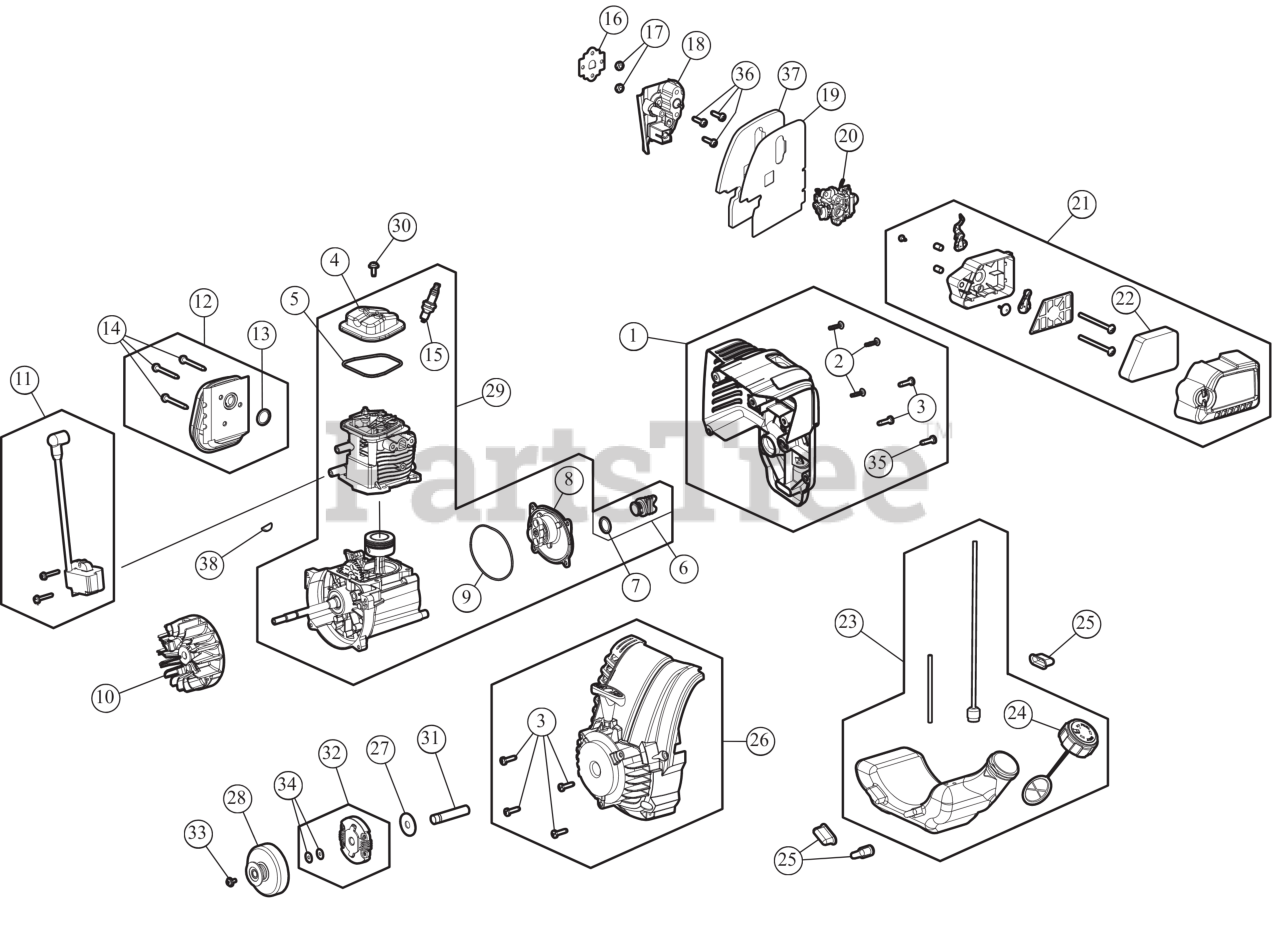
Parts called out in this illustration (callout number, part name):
1	REAR ENGINE CVR
2	SCREW 8-16 x 3/4
3	SCREW M5-0.8 x 19
4	ROCKER COVER
6	OIL PLUG
7	RING, OIL PLUG (AC
8	CRANKCASE COVER
9	O-RING CRNKCSE CVR
10	FLYWHEEL ASSEMBLY AC3.1
11	MODULE ASSEMBLY
12	MUFFLER ASSEMBLY
13	GASKET/MUFFLER
14	SCREW M5 x 44MM
15	SPARK PLUG 4 CYCL
16	GASKET/INSULATOR
18	CARB INSULATOR
20	CARBURETOR
21	AIR CLEANER COVER
22	AIR FILTER
23	FUEL TANK ASSEMBLY
24	FUEL CAP ASSEMBLY 43MM-6 W/O HOLE
25	FUEL TANK PADS
26	STARTER HOUSING
27	WASH, CLUTCH O.D. 1.155 +/- .0
28	CLUTCH DRUM/PULLEY
29	SHORT BLOCK
30	SCR, VALVE COVER
31	SPACER :2.165"
32	CLUTCH WITH SPACER
33	SCREW 8-32X.375 PH S
34	WASH, NORAM CLUTCH
35	SCR, M5 x 15.8MM
36	SCREW, M5 X18
37	HEAT SHIELD
38	WOODRUFF KEY #403-.125 x .375
